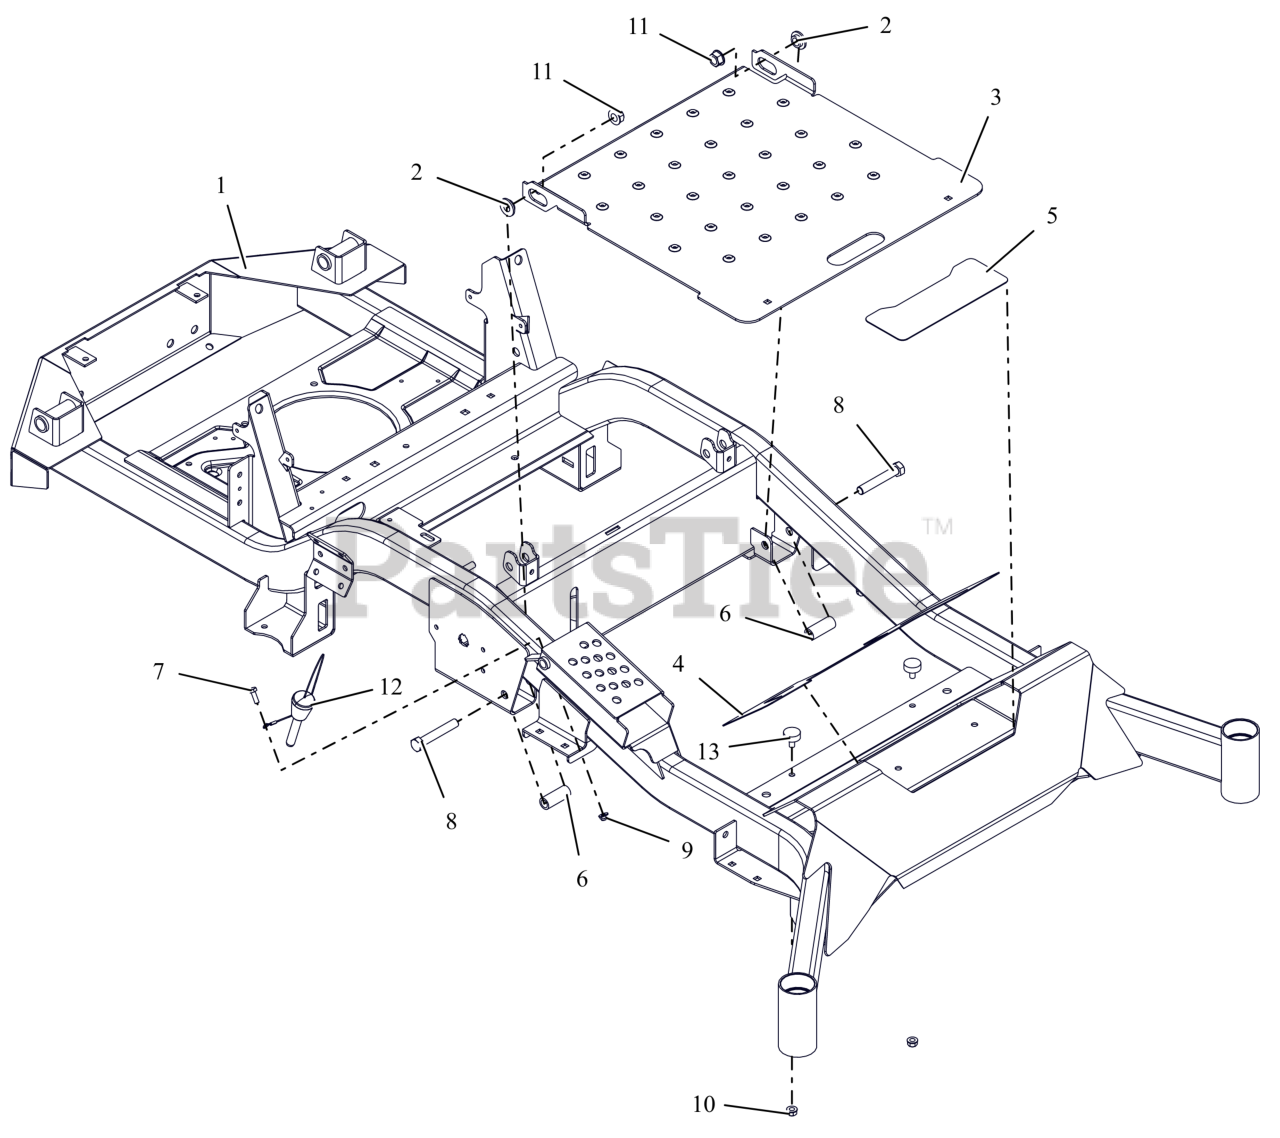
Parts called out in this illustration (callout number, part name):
1	APEX 60"FRAME W/SAFTETY DECALS
2	BSHG-FLG .515X.750X.395X1.120
3	PANEL, ACCESS
4	GRIP, FRONT
5	GRIP, STEP
6	SPACER, .515X.75X1.83
7	BLT, HEX .25-20X.75 G5 ZCC
8	BLT, HEX .50-13X3.00 G5 ZCC
9	NUT,NYL-FLG .25-20 GF ZCC
10	NUT,SPNLK-FLG .31-18 G5 ZCC
11	NUT-LK-TOP-FLG .500-13 GF ZCC
12	PIN, MAGNETIC .50X2.50
13	BUMPER, RUBBER
